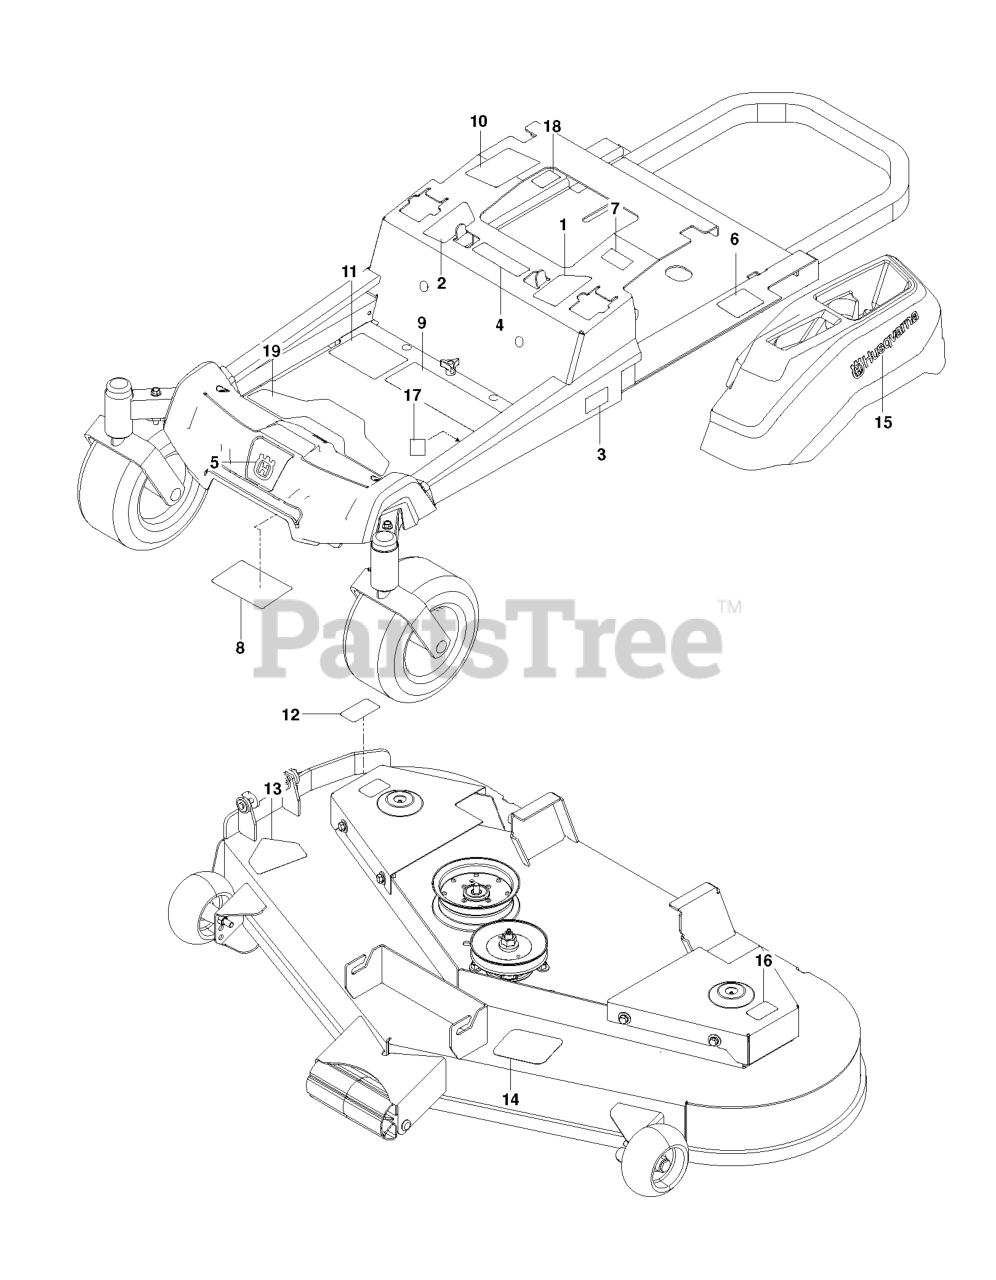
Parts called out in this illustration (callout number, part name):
1	DECAL.ZTR.RZ.THRTL/PRKBRK.V2.L
2	DECAL.ZTR.RZ.THRTL/PRKBRK.V2.R
3	DECAL.ZTR.SIDERAIL.MN.Z248F.HU
4	EURO DECAL-BATTERY WARNIN6
5	DECAL.BADGE.55MM.CROWNH.HUSQ
6	DECAL, DO NOT TOW
7	DECAL, EXITING MOWER
8	DECAL, SERVICE
9	DECAL.ZTR.WARNING.SMARTIGNITIN
10	DECAL, CUSTOMER RESPNSIBILITY
11	DECAL.ZTR.STARTINSTRCT.CHOKE15
12	DECAL.DECK.6MIL./DEF.SHLD.WARN
13	DECAL, DECK DEFLECTOR, WARNING
14	DECAL, BELT ROUTING
15	DECAL.HUSQVARNA.210MM
16	DECAL.DECK.6MIL.EURO.NOSTEP
17	DECAL.80.DBA.AUSTRALIA
18	DECAL CERTIFICATION DECAL EMCC
19	PAD.RZ.FOOTREST.PLATE
